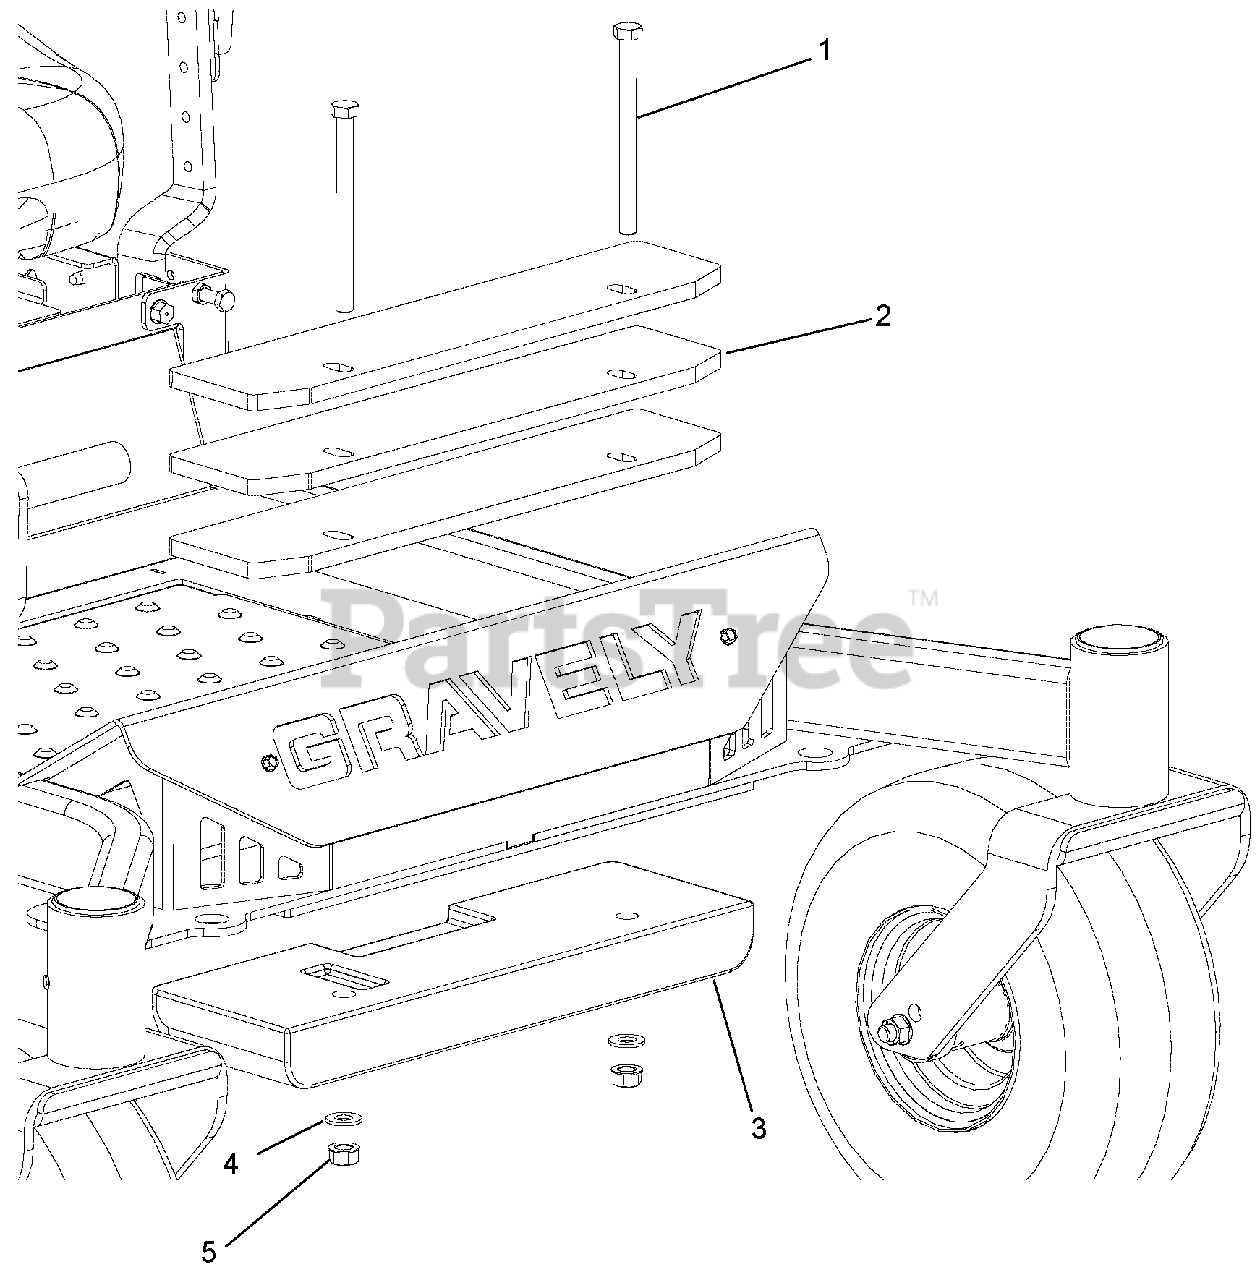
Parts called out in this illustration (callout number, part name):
1	Bolt, Hex .50-13 x 4.50
2	Plate, Counterweight
3	Plate, Cast Iron
4	Washer, Flat Steel .531 x 1.06 x .095
5	Nut, Locking Nylon Flange .50-13
